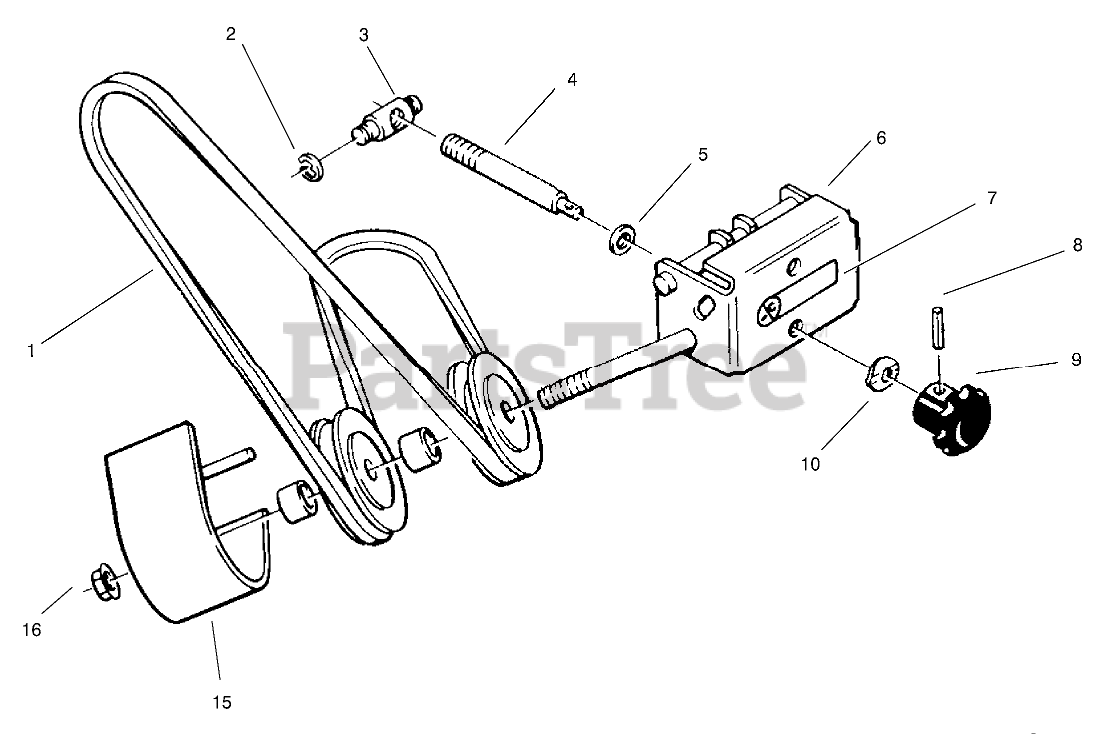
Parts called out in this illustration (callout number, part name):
1	V-BELT
2	RING-RETAINING
3	TRUNNION-DOUBLE
4	ROD ADJ
5	WASHER-FLAT
6	WA FRONT SUPPORT (RED)
7	DECAL-ATTACH A-MATIC
8	PIN-ROLL
9	KNOB-ADJUSTMENT
10	WASHER-SPRING
11	PULLEY-IDLER
12	SPACER
13	Decal-A-80 (E)
14	SPACER-OUTER
15	COVER WA - BELT (RED)
16	Nut
